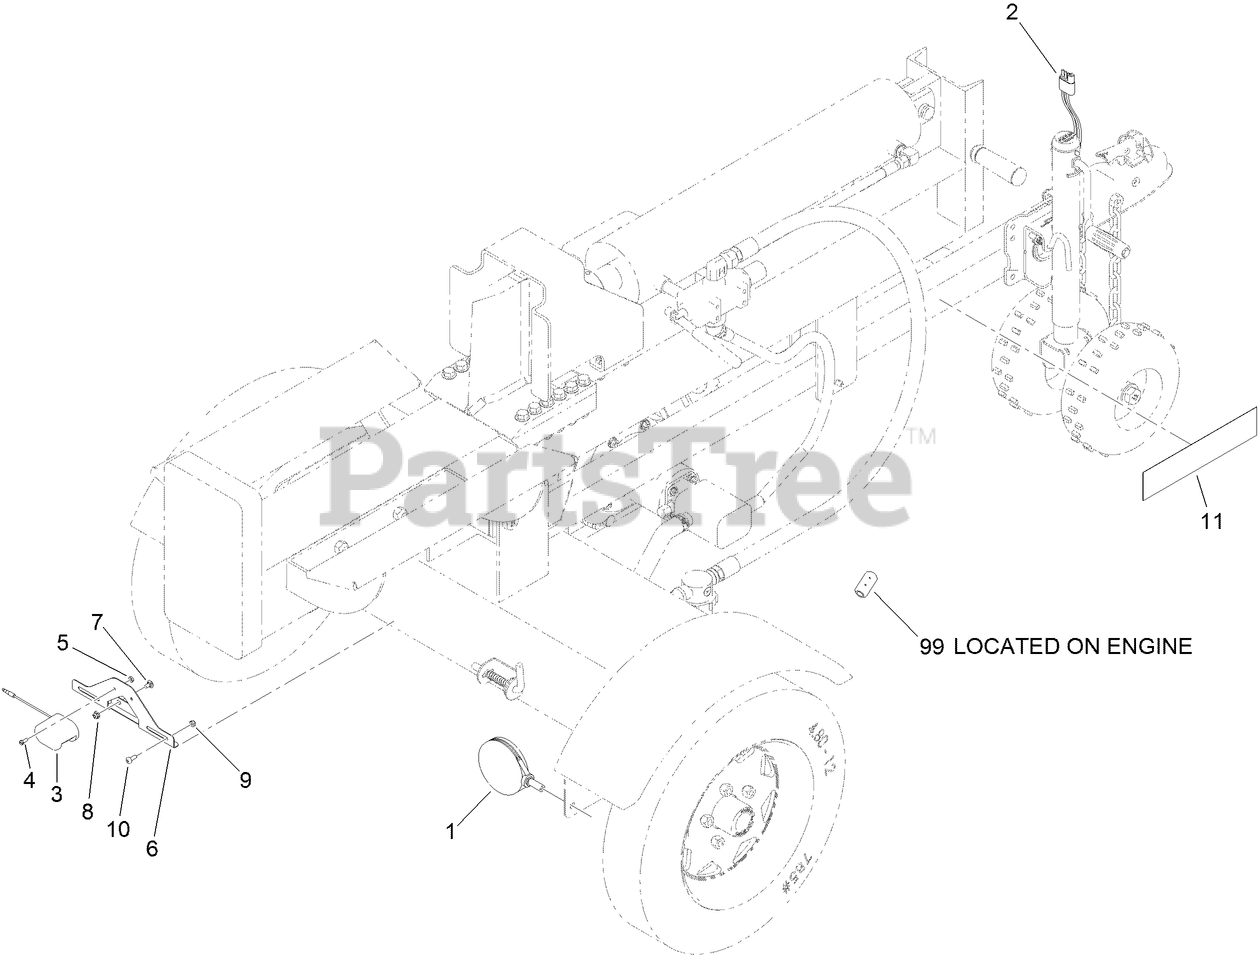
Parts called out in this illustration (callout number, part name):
1	LIGHT-TAIL
2	HARNESS-TRAILER
3	LAMP-LICENSE
4	SCREW-SHH
5	NUT-LOCK, NI
6	BRACKET-PLATE, LICENSE
7	SCREW-CARR
8	NUT-HF
9	NUT-LOCK
10	SCREW-PPH
11	DECAL-VIN/TIRE
99	FERRITE-SNAP ON
